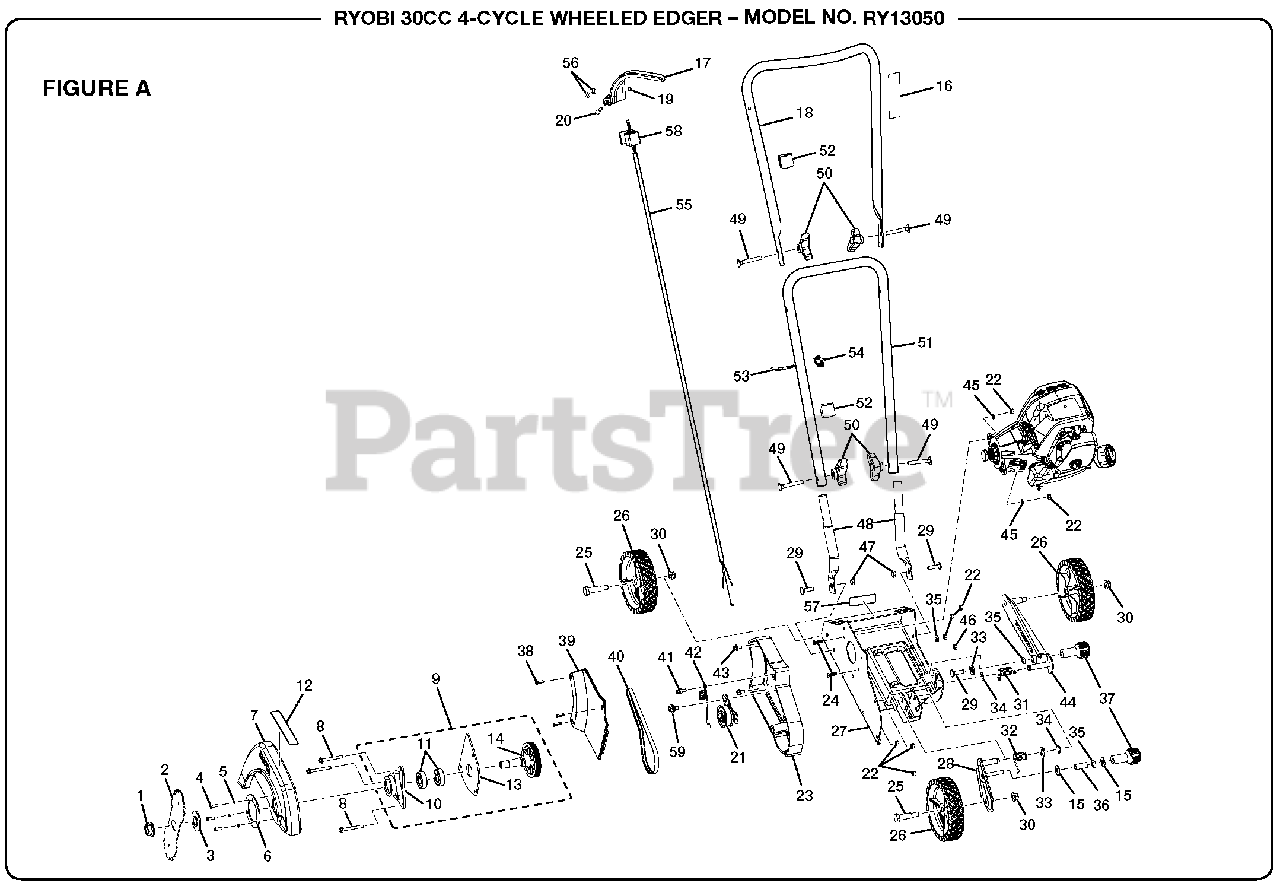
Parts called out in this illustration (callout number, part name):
1	Blade Nut (M16, Flanged)
2	Edger Blade
3	Flanged Washer
4	Screw (10-24 x 5/8 in, Hex Hd.)
5	Lock Washer (5mm)
6	Ring Washer
8	Bolt (M6 x 55 mm)
9	Front Pulley Assembly
10	Bearing Plate
11	Ball Bearing (6203-2RS)
12	Warning Label (Guard)
13	Mounting Plate
14	Blade Shaft and Pulley Assembly
16	Warning Label (Upper Handle)
18	Upper Handle Assembly
20	Pivot Pin
21	Idler Pulley Assembly
22	Lock Nut (M6)
23	Guard Cover Base
24	Screw (M6 x 20 mm)
25	Shoulder Bolt (M10 x 34 mm)
26	Wheel Assembly (6 in.)
27	Edger Base w/Bushings
28	Front Wheel Bracket Assembly
29	Handle Bar Bolt (M8)
30	Lock Nut (M10, Flange)
31	Axle Spring
32	Front Axle Spring
33	Washer (M13)
35	Lock Washer (M8)
36	Front Axle Bushing
37	Wheel Adjuster Knob
38	Bolt (M6 x 16 mm, Thread Forming)
39	Belt Cover
41	Shoulder Bolt (M6 x 17 mm)
42	Idle Pulley Spring
43	Bolt (M6 x 12 mm)
44	Bracket Assembly
45	Washer (6 mm)
46	Hex Nut (M8)
47	Flange Nut (M8)
48	Handle Post
49	Carriage Bolt (M8 x 60 mm)
50	Knob Assembly
51	Lower Handle
52	Cable Clip
53	Hook Screw (M5 x 18 mm)
54	Wing Nut (M5)
55	Throttle Cable Assembly
56	Plastic Washer
57	Warning Label (Combustion)
59	Shoulder Bolt (M8)
